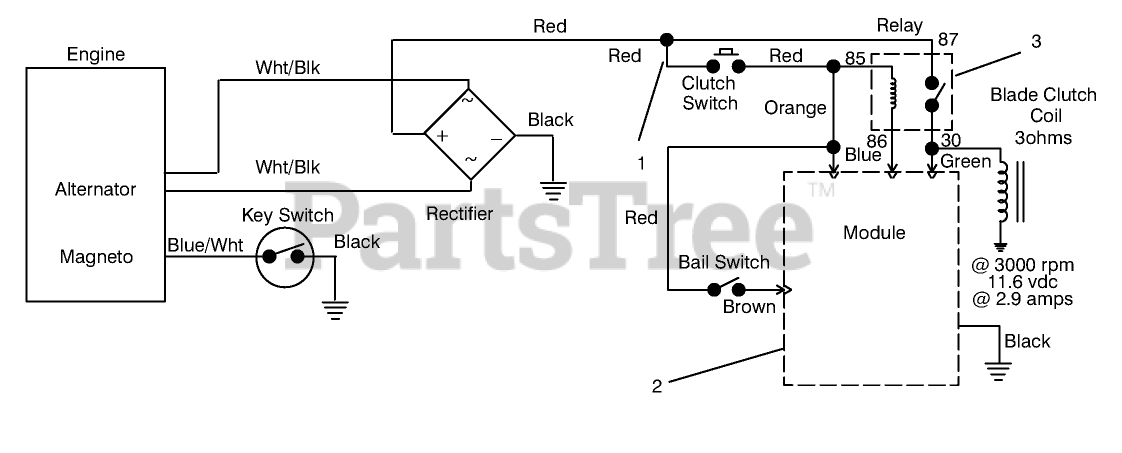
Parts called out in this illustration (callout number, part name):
1	Wire Harness
2	MODULE
3	RELAY
